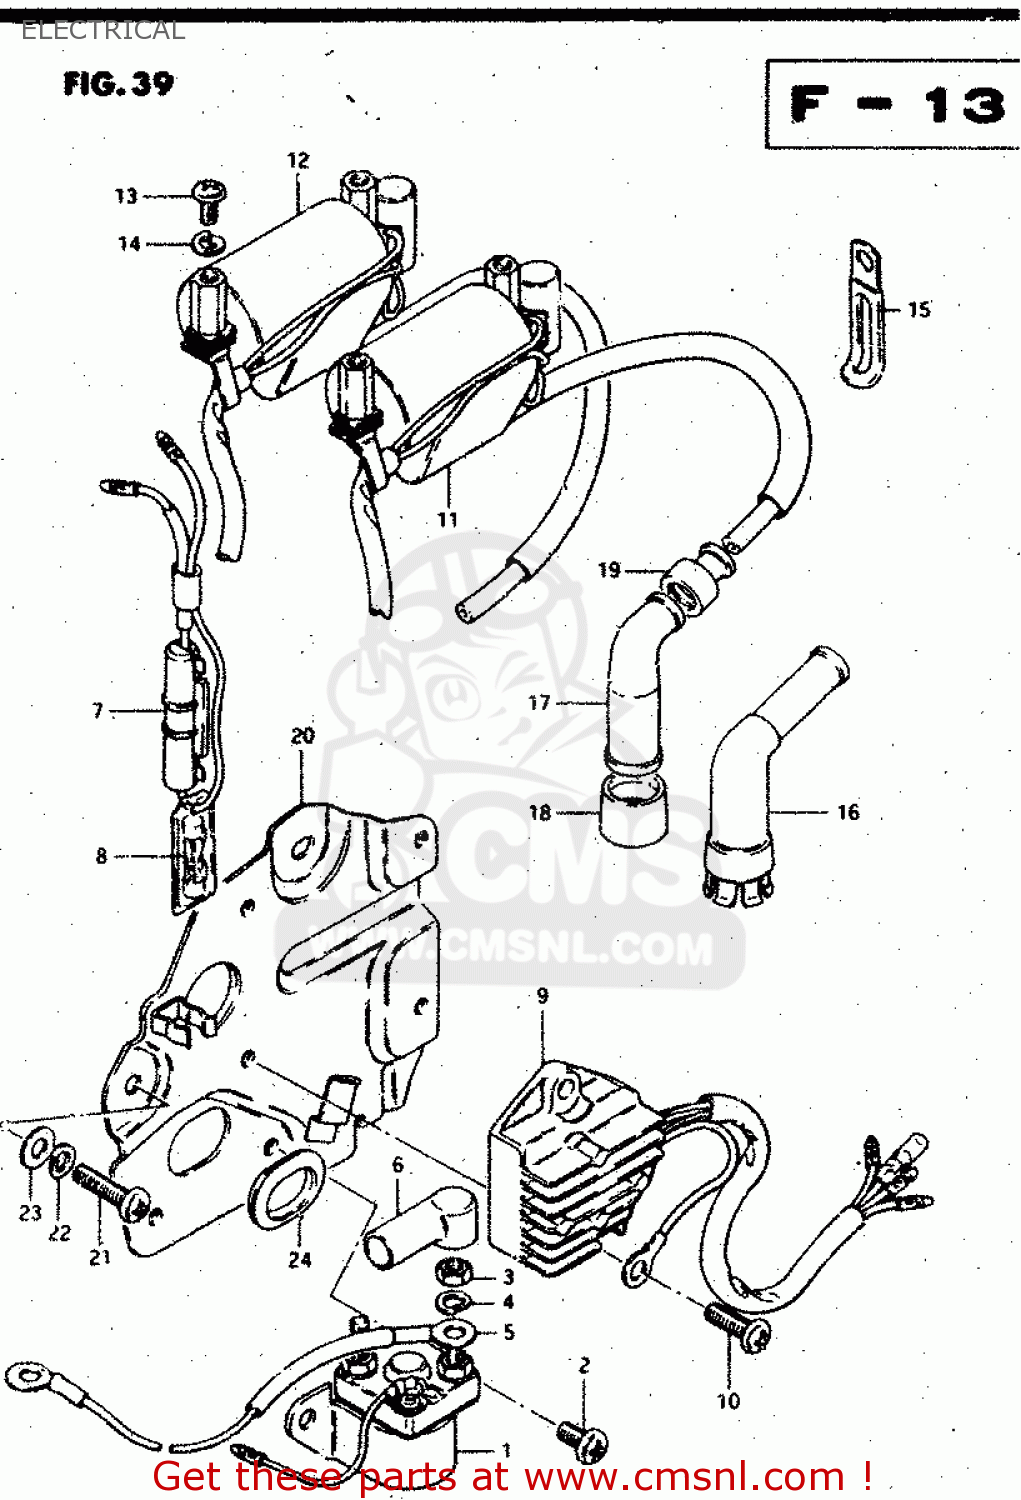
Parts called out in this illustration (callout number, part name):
1	RELAY ASSY,STARTING MOTOR
2	SCREW
3	NUT 6MM
4	LOCK WASHER
5	CORD,BATTERY MINUS
6	CAP,STARTER RELAY
7	BOX ASSEMBLY,FUSE
8	FUSE(15A)
9	RECTIFIER ASSEMBLY
10	SCREW
11	COIL, IGNITION LH
12	COIL, IGNITION RH
13	SCREW
14	LOCK WASHER
15	CLAMP L:35
16	CAP, SPARK PLUG (S)
17	CAP,SPARK PLUG
18	SEAL,SPARK PLUG
19	SEAL,SPARK PLU
20	PLATE,ELECTRIC PARTS H
21	SCREW
22	LOCK WASHER
23	WASHER
24	GROMMET
